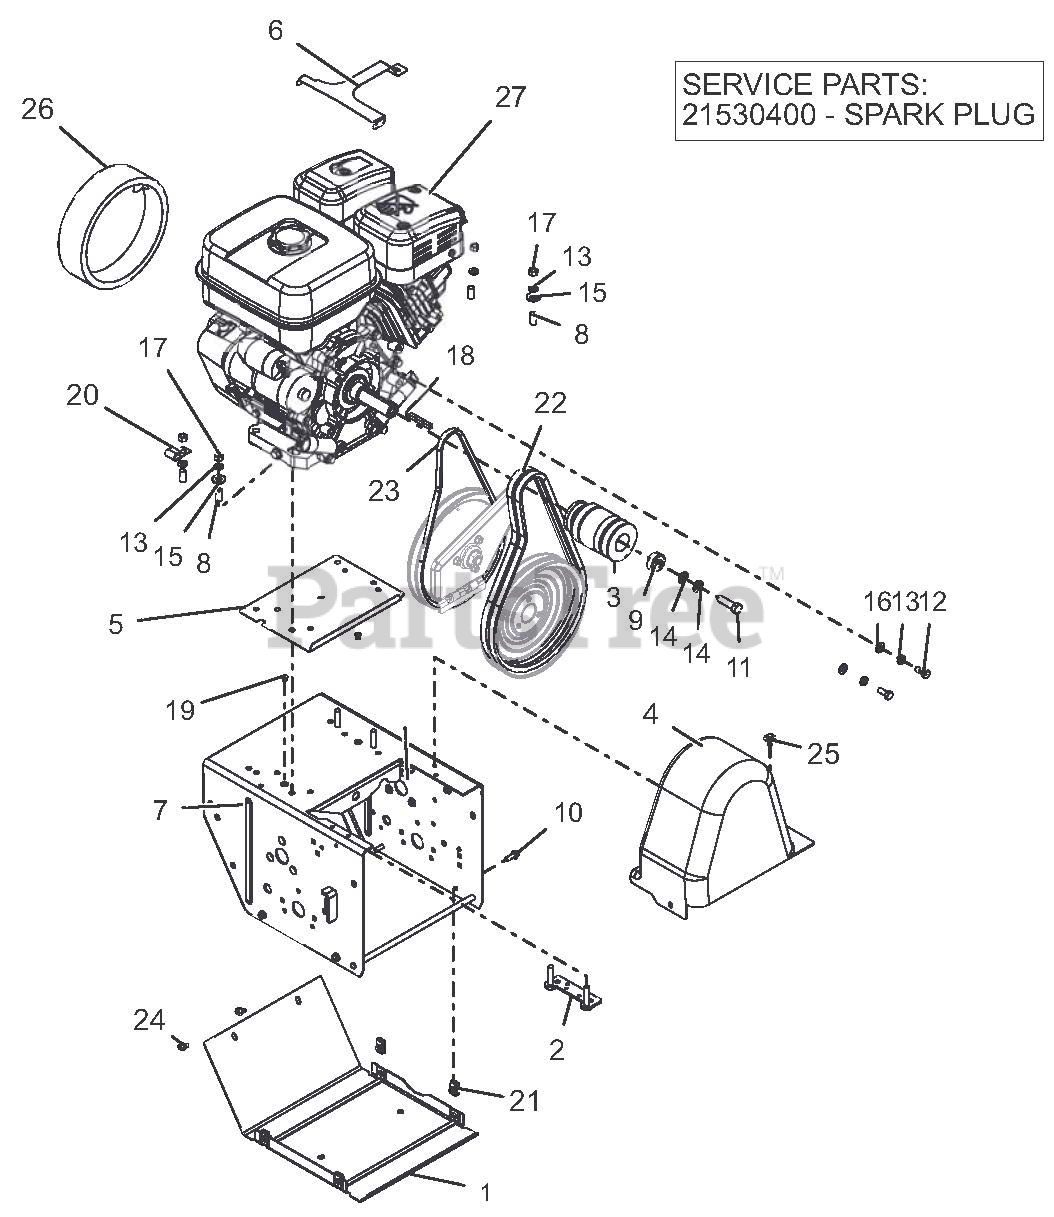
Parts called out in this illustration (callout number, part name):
1	COVER, BOTTOM
2	STRAP, ENGINE BOLT-LARGE BRIGG
3	SHEAVE, SUBARU EX27
4	COVER, BELT-TALL PRO
5	BAFFLE, WATER-PRO SERIES
6	GUARD, SNOW-SUBARU
7	PRO HYDRO FRAME, MAIN
8	BSHG-SLV .325X.400X.795
9	BSHG-SPACER .47X1.25X.50
10	BLT-HEX .25-20X.75 HWH YZ GR5
11	BLT-HEX .44-20X1.50 G5 YZ EP80
12	BLT-HEX .31-24X.75 YWZC GR5
13	WSHR-LK .312X.097 HVY YWZC
14	@WSHR-LK .44X.109 REG YWZC
15	@WSHR-FL-STL.38X.875X.083 YWZC
16	@WSHR-FL-STL.344X.688X.065YWZC
17	@NUT-HEX .31-18 YWZC
18	KEY .25X.25X2.25
19	RVT-POP .187 YZ
20	J-CLAMP
21	NUT-RTNR .25-20X.56
22	V-BELT, HA-RAW EDGE (SET)
23	V-BELT, 3L-RAW EDGE
24	SCR-TAP .25-20X.50 HWH TR YWZ
25	SCR-TAP .25-20X.50 LGHWH TR YZ
26	FOAM COVER, RECOIL-SUBARU
27	ENGINE,SUBARU EX27 AS 120V
27	PLUG, SPARK - TEC. SNO-THRO
27	KEY, PUSH/PULL SUBARU
